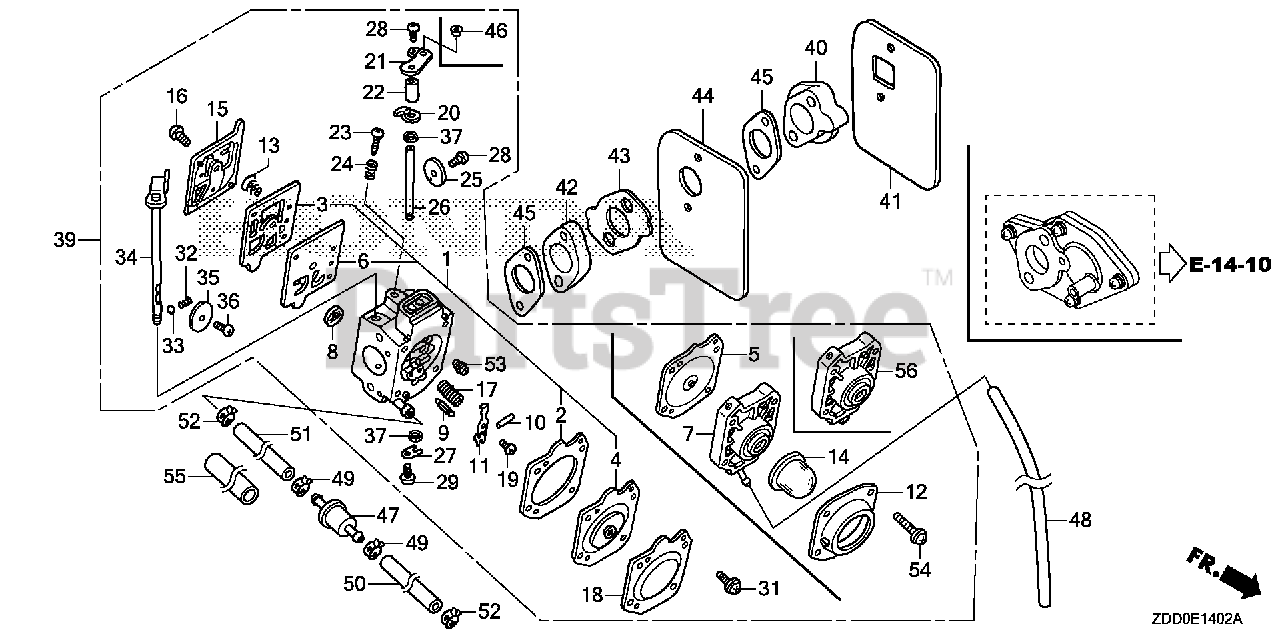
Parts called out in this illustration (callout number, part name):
2	GASKET, METERING DIAPHRAGM (CARBURETOR NO.)
3	GASKET, PUMP
5	DIAPHRAGM ASSY., METERING (CARBURETOR NO.)
6	DIAPHRAGM, PUMP
7	BODY ASSY., AIR PURGE (CARBURETOR NO.)
8	SCREEN, INLET (CARBURETOR NO.)
9	VALVE, INLET NEEDLE
10	PIN, METERING LEVER
11	LEVER, METERING
12	COVER, PRIMER PUMP (CARBURETOR NO.)
13	SPRING, PUMP
14	PUMP, PRIMER (CARBURETOR NO.)
15	COVER, PUMP (CARBURETOR NO.)
17	SPRING (CARBURETOR NO.)
19	SCREW (CARBURETOR NO.)
20	STOPPER, THROTTLE LEVER
21	LEVER, THROTTLE (CARBURETOR NO.)
22	SPACER, THROTTLE LEVER
23	SCREW, IDLE ADJUSTING (CARBURETOR NO.)
25	VALVE, THROTTLE (CARBURETOR NO.)
26	SHAFT, THROTTLE (CARBURETOR NO.)
27	CLIP, THROTTLE SHAFT
28	SCREW, VALVE
29	SCREW ASSY. (CARBURETOR NO.)
34	SHAFT ASSY., CHOKE (CARBURETOR NO.)
35	VALVE, CHOKE (CARBURETOR NO.)
39	CARBURETOR ASSY. (HDA 278C)
40	INSULATOR, CARBURETOR
41	GASKET, INSULATOR
42	INSULATOR B, CARBURETOR
43	GASKET B, INSULATOR
44	PLATE, INSULATOR
45	GASKET, CARBURETOR
46	COLLAR, LEVER
47	STRAINER, FUEL
49	CLAMP, TUBE (D9.4)
50	HOSE, FUEL (4.2X80) (FKM)
50	HOSE, FUEL (4.2X80)
51	HOSE, FUEL (4.2X330)
52	CLIP, TUBE (D8.5)
53	JET (#46) (CARBURETOR NO.)
53	JET (#48) (CARBURETOR NO.)
53	JET (#50) (CARBURETOR NO.)
53	JET (#52) (CARBURETOR NO.)
54	SCREW ASSY. (CARBURETOR NO.)
55	BULK HOSE, VINYL (11X13X3000) (11X13X210)
